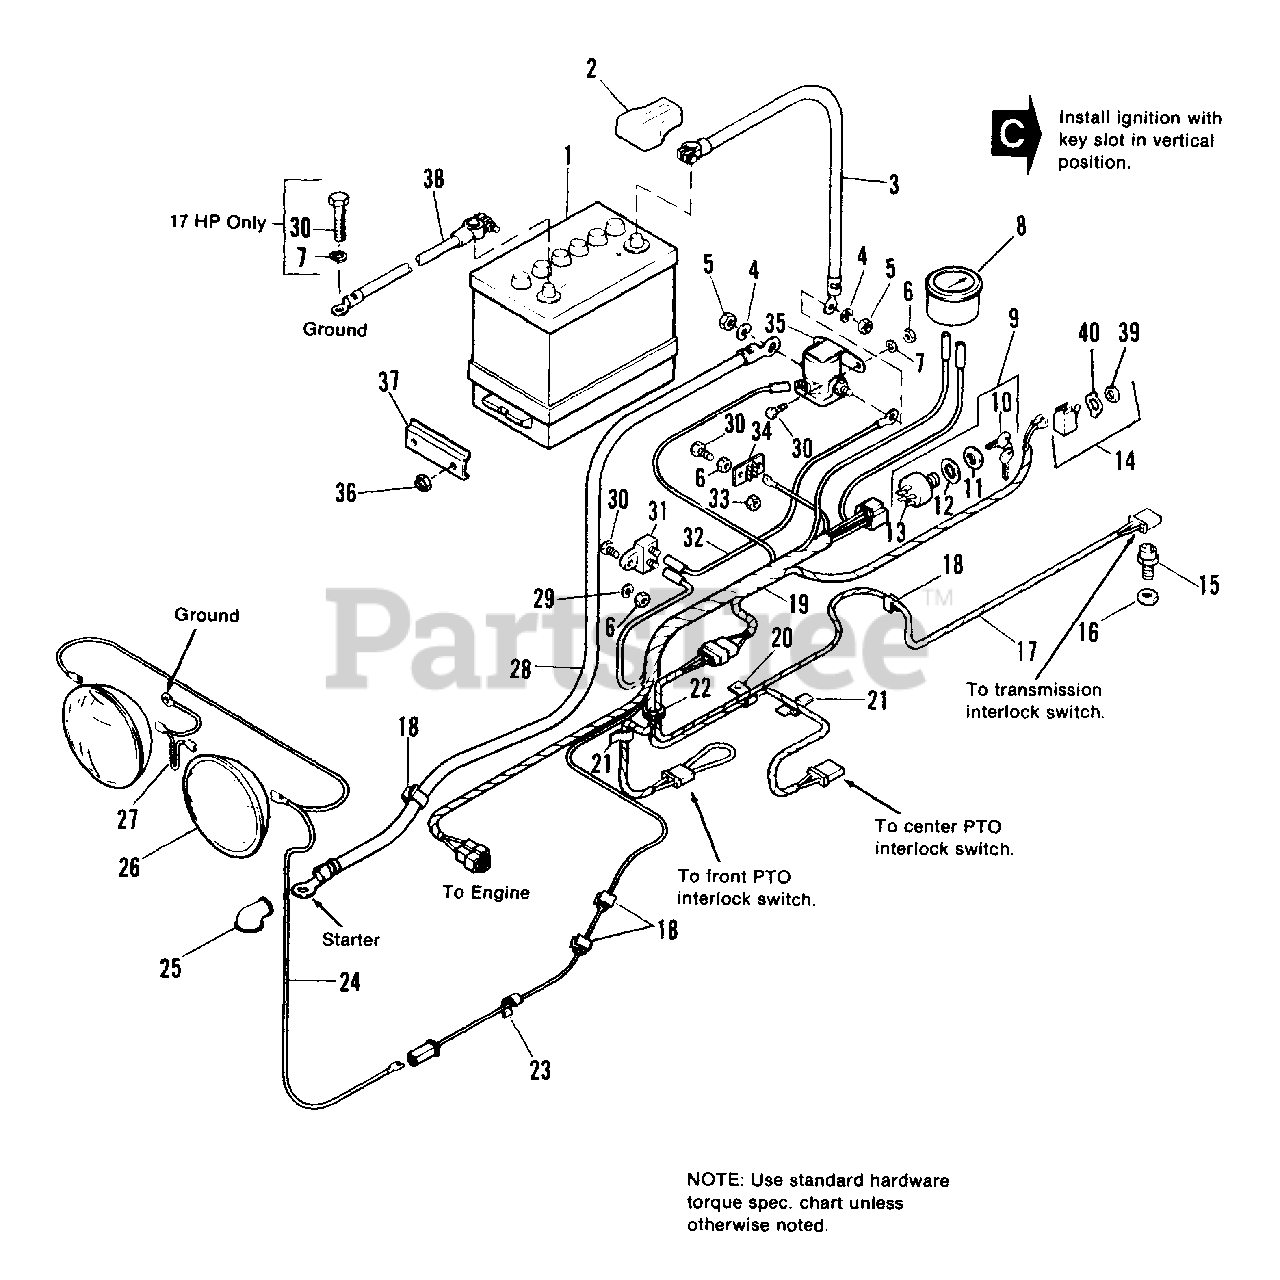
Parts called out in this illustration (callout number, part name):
1	BATTERY (Includes Decal)
2	PROTECTOR, Terminal
3	CABLE (Battery to Ground)
4	LOCKWASHER, 5/16
5	NUT, Hex, Full, 5/16-18
6	NUT, Hex, Full, 1/4-20
7	LOCKWASHER, 1/4 (Qty 2 on 7114)
9	SWITCH & KEY ASSY., Ignition
10	KEY SET (2)
11	NUT, Special
12	LOCKWASHER, Internal, 5/8
14	SWITCH, Toggle
15	SWITCH, Interlock
16	NUT, Pal
17	WIRE ASSY.
18	CLIP, Tinnerman
19	HARNESS ASSY.
20	CLIP, Cable
21	CLIP, Wire
23	CLIP, Tinnerman
25	COVER. Terminal
26	LAMP, Sealed Beam, G.E., #4411-1
27	WIRE ASSY.
28	CABLE (Solenoid to Starter)
29	LOCKWASHER, 1/4
30	CAPSCREW, Hex Hd., 1/4-20 x 5/8 (Qty. 5 on 7114)
31	CIRCUIT BREAKER
33	LOCKNUT, Hex, 1/4-20
34	BOARD, Terminal
35	SOLENOID, Starter
36	NUT, Elastic, 5/16-18
38	CABLE (Battery to Ground)
39	NUT, Switch
